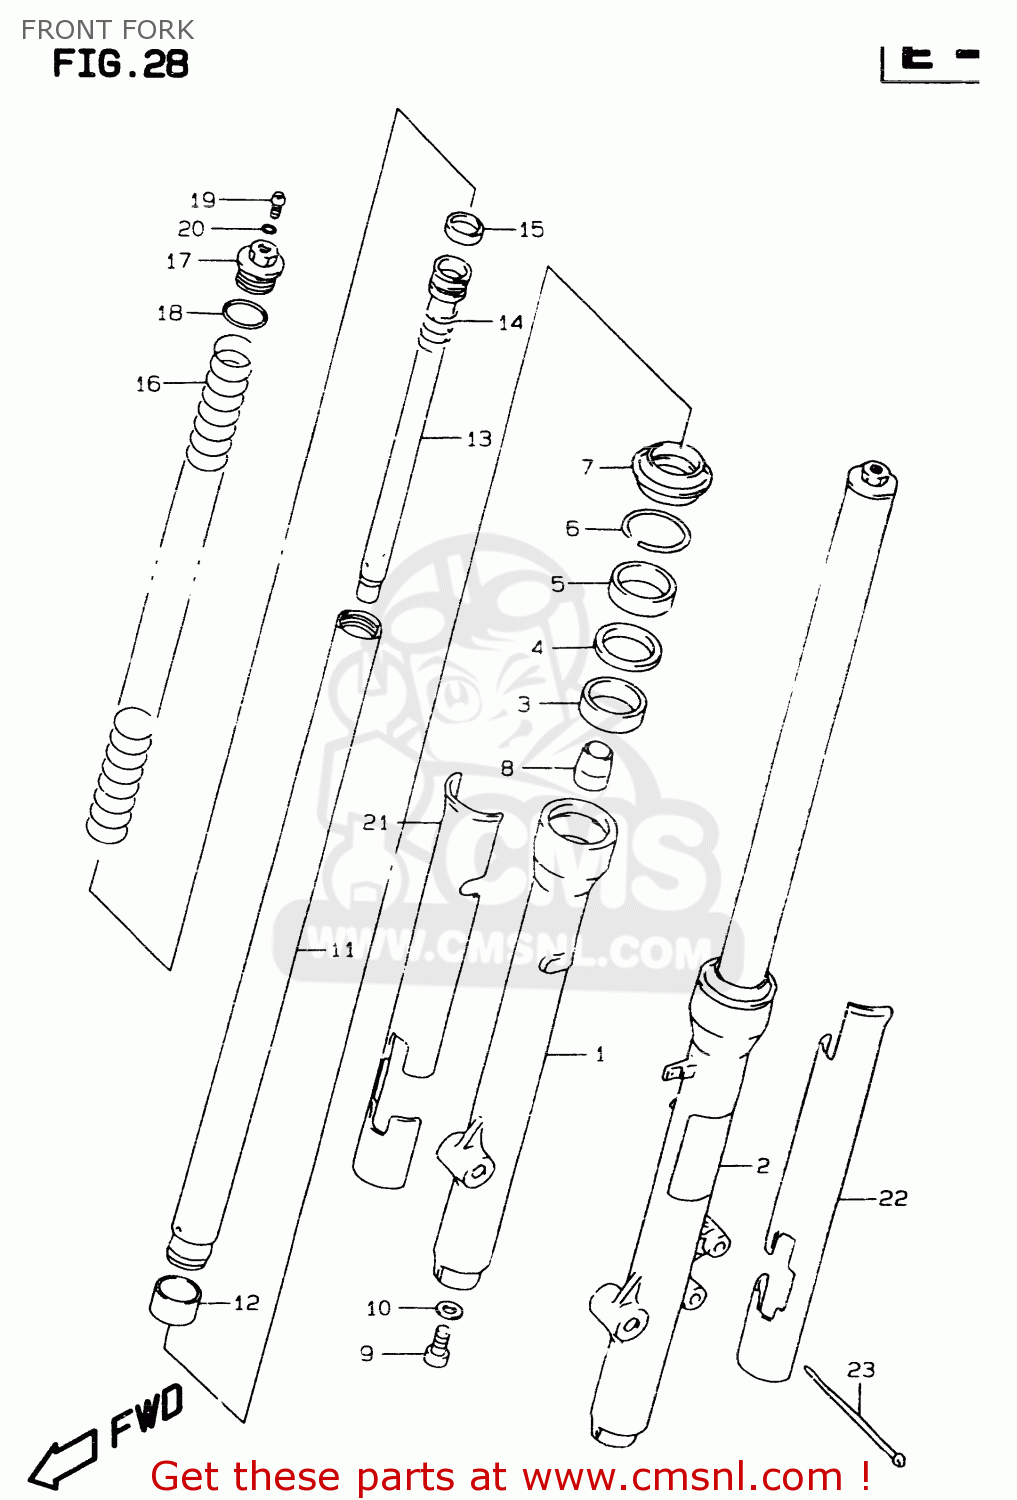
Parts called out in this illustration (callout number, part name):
1	TUBE,OUTER,R
2	TUBE,OUTER,L
3	BUSH,GUIDE
4	SPACER,SEAL
5	SEAL,OIL 35X48X11
6	RING,OIL SEAL STOPPER
7	SEAL,DUST
8	PIECE,OIL LOCK
9	BOLT(8X27)
10	GASKET (NAS)
11	TUBE,INNER
12	PISTON
13	SEAT,UNDER
14	SPRING,REBOUND
15	RING,PISTON
16	SPRING,UNDER
17	BOLT,FORK
18	O RING
19	BOLT,PLUG
20	O RING
21	PROTECTOR,FR FORK,R
22	PROTECTOR,FR FORK,L
23	CLAMP(L:250)
